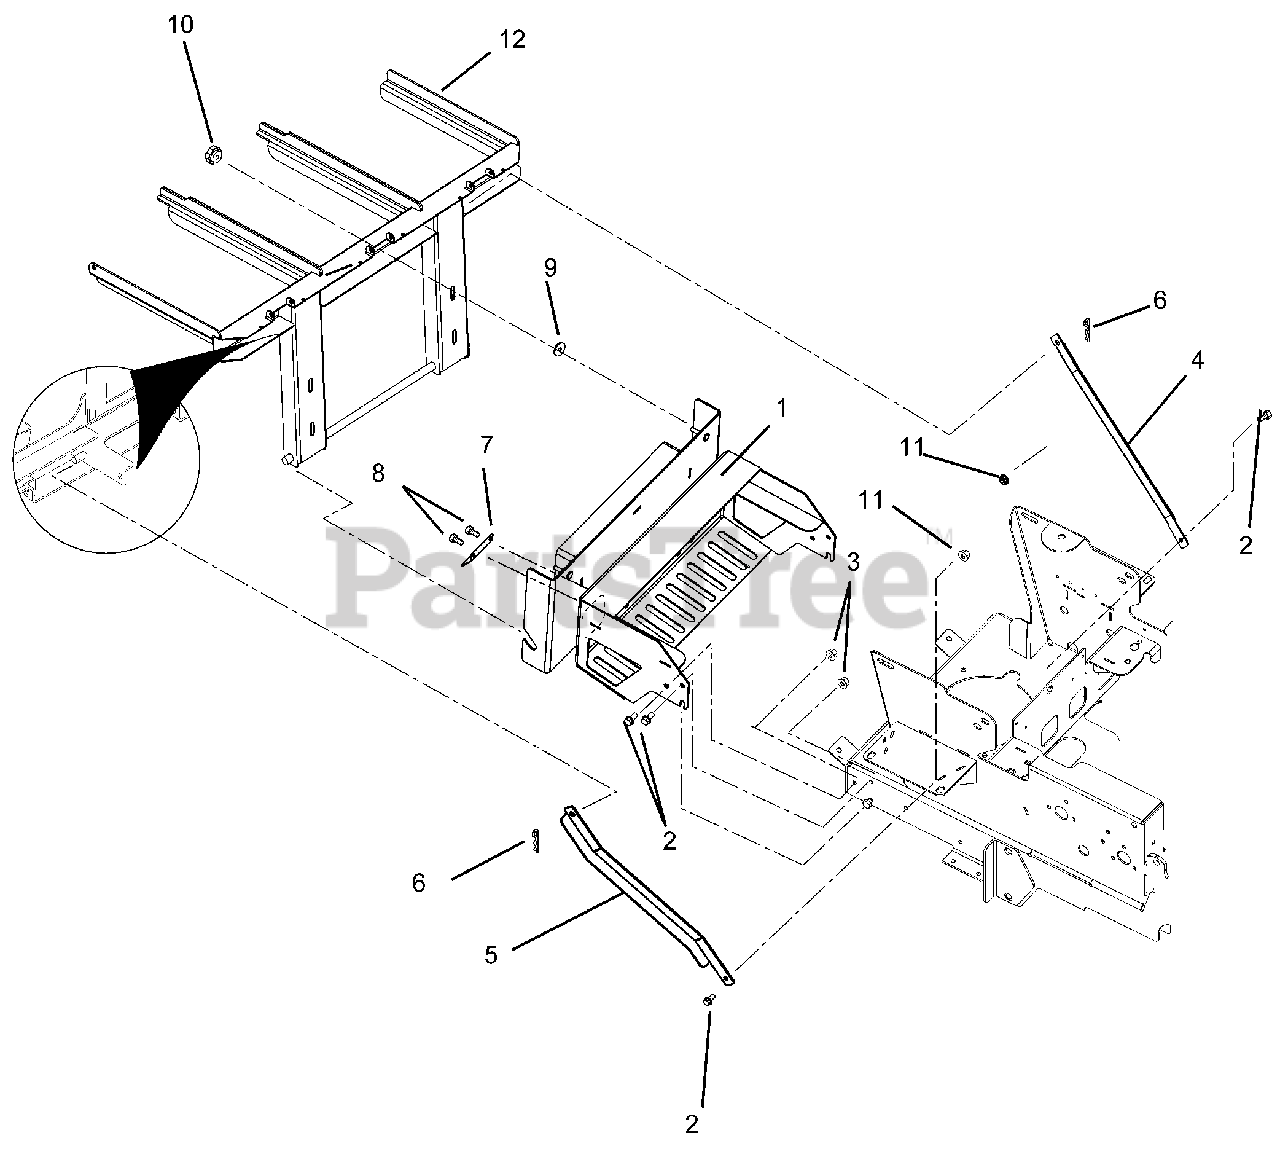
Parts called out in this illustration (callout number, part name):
1	Weldment, Bagger Head Mount
2	Bolt, Hex .38-16 x 1.00 Grade 5
3	Nut, .38-16 Nyloc Flange
4	Weldment, Left Bagger Support
5	Weldment, Right Bagger Support
6	Pin, Hair #25
7	Shield, Heat Deflection
8	Screw, Tapping .38-16 x 0.50
9	Washer, Flat Steel .563 x 1.38 x .105
10	Knob, Clamping .312-18 Nyloc
11	Nut, Center Lock .38-16
12	Weldment, XL Bagger Frame
